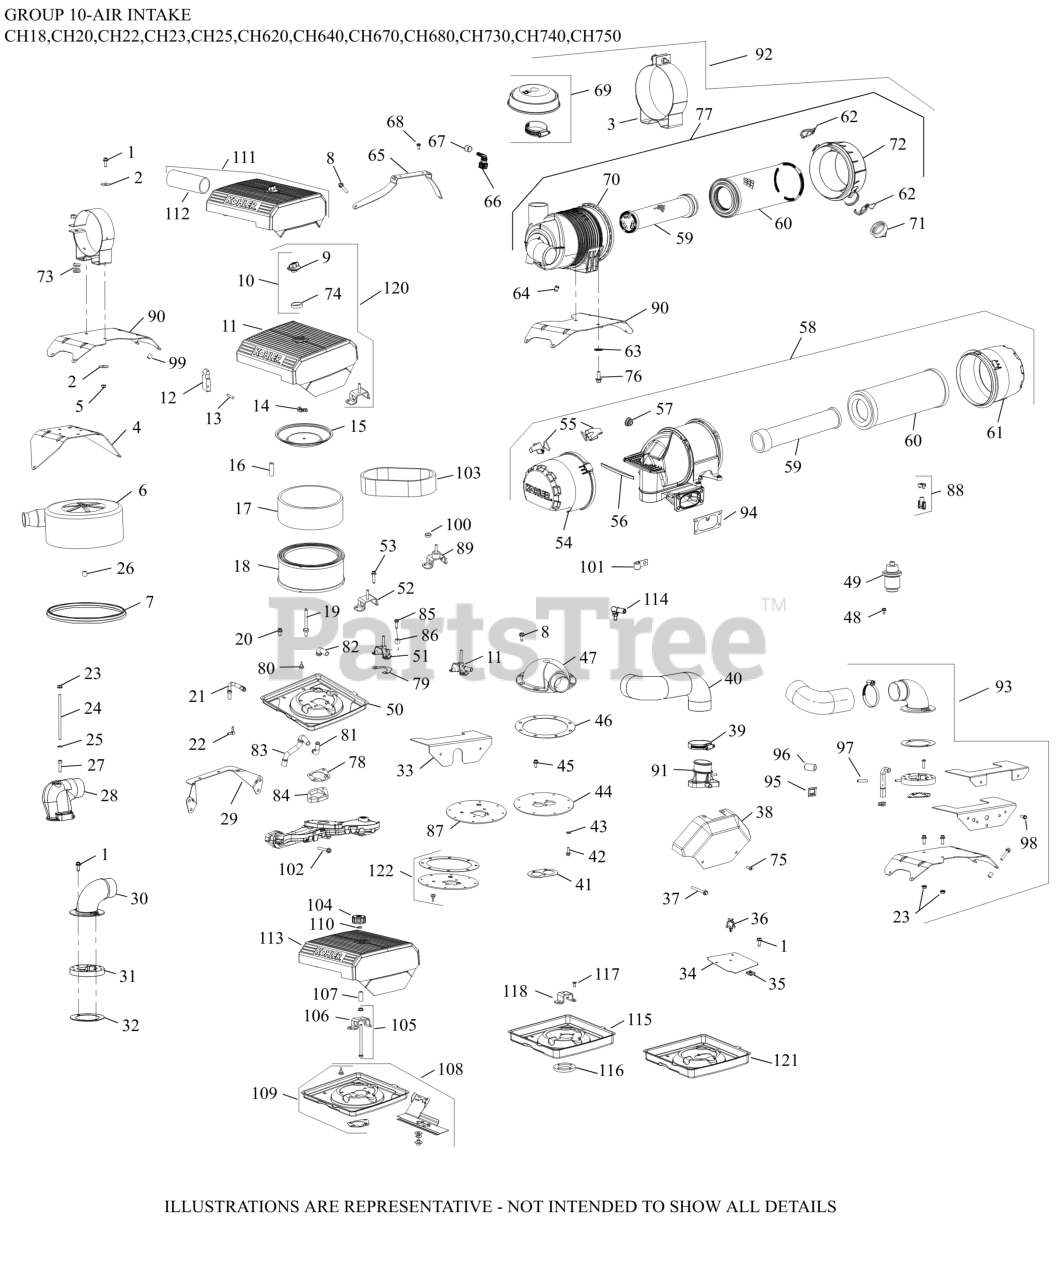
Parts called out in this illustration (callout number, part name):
1	SCREW, IND SLT HD 10-32X1/2"
9	KNOB, COVER
10	KIT, KNOB W/SEAL
11	COVER, AIR CLEANER
14	NUT, WING
15	COVER, INNER AIR CLEANER
16	SEAL BREATHER
17	PRE-CLEANER (HIGH)
18	AIR FILTER ELEMENT
37	SCREW, FLG M6X1.0X55
115	BASE, AIR CLEANER
118	BRACKET, AIR CLEANER
120	KIT, AIR CLEANER COVER
NI	MANIFOLD, INTAKE
